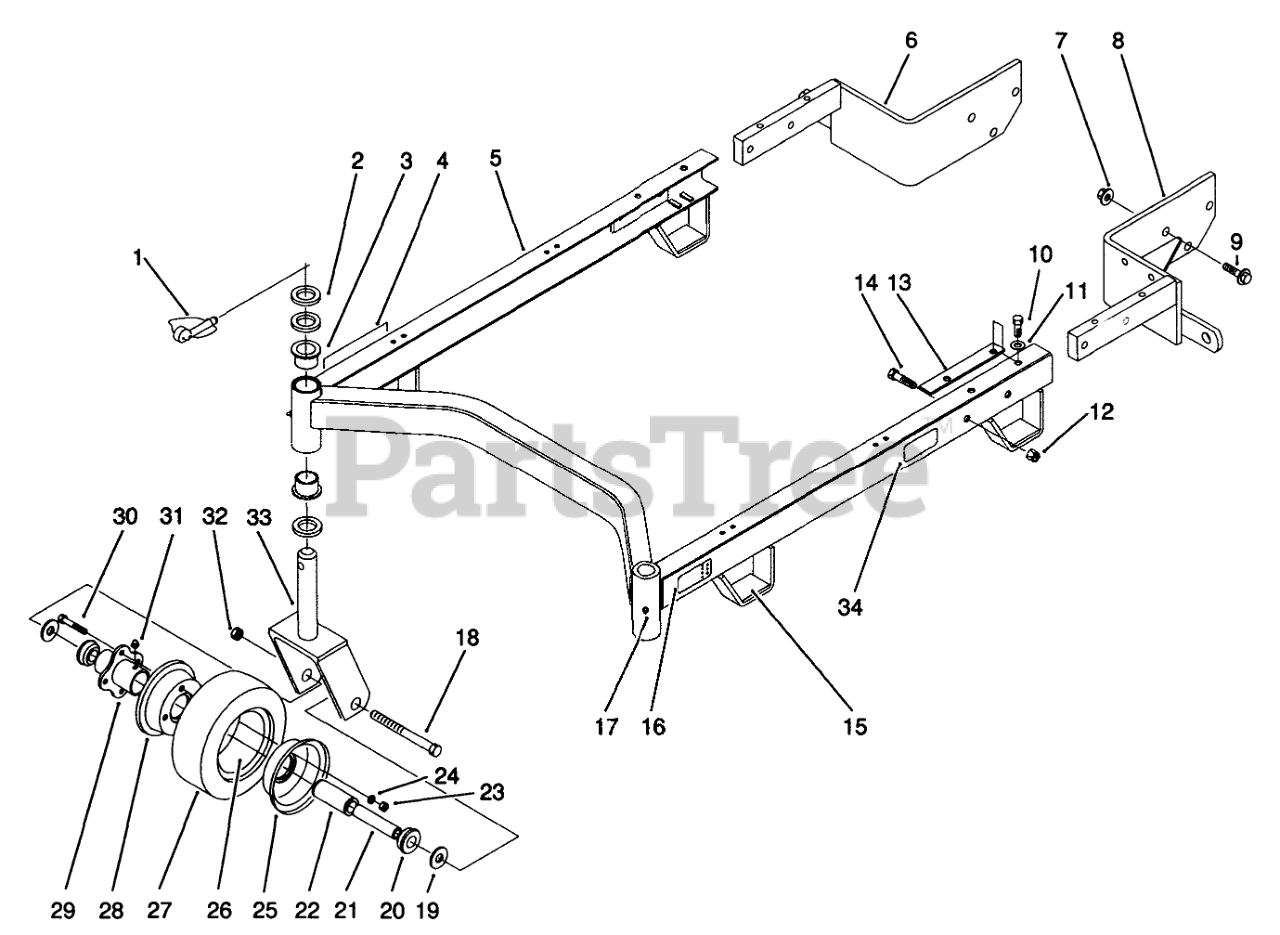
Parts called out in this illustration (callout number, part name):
1	PIN-LYNCH
2	WASHER-THRUST
3	Bushing
4	DECAL-HOC, LH
5	Suspension Frame W.A.
6	Angle Bracket Ass-y R.H.
7	NUT-HF
8	Angle Bracket Ass-y L.H.
9	SCREW-HHF
10	SCREW W/PATCH
11	WASHER-FLAT
12	NUT-LOCK, CONE
13	SHIM-CARRIER
14	SCREW-HH
15	CUSHION-RUBBER
16	DECAL-HOC, RH
17	FITTING-GREASE
18	SCREW-HH
19	WASHER-FLAT
20	BEARING-OUTSIDE
21	SPANNER-TIRE
22	BEARING-ROLLER
23	NUT-HEX
24	WASHER-LOCK
25	MALE WHEEL HALF
26	TUBE-INNER (W/VALVE)
28	FEMALE WHEEL HALF
29	HUB-CENTER
30	WHEEL BOLT
31	FITTING-GREASE
32	NUT-HEX
33	Castor Fork
34	DECAL - HOC
